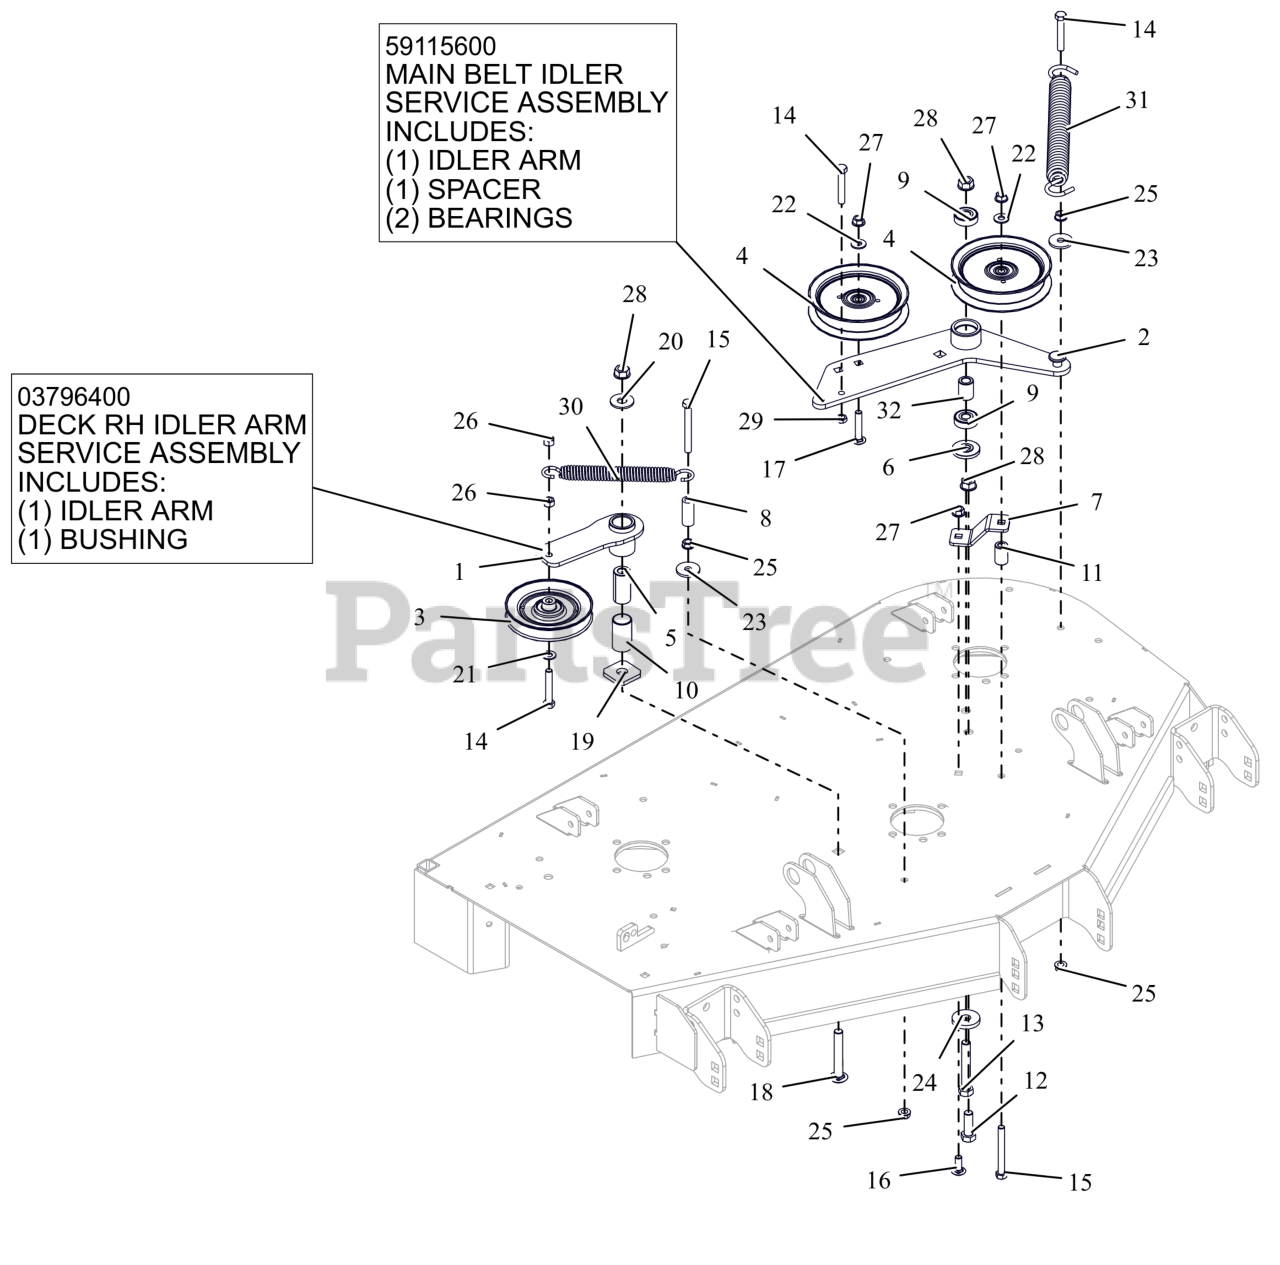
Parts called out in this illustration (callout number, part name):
1	WMT, IDLER ARM - BLACK
1	ASM, IDLER ARM (DECK)
2	WLDMT, DECK PTO IDLR ARM
2	ASSEMBLY, MAIN BELT IDLER
3	IDLER, V-5.00"
4	IDLER, FLAT 5.00"
5	BSHG, SPCR .502X.997X2.03 PM
6	SPACER, IDLER ARM
7	PTO FIXED IDLER MTG BRKT -RED
8	HOSE, .38 X 1.65
9	BRG-BALL .500X1.38X.437
10	BSHG, 1.00X1.125X1.937
11	BUSHING, SLV .380X.750X1.190
12	BLT,HEX .50-13X1.50 G5 ZCC
13	BLT,HEX .50-13X3.25 G5 ZCC
14	BLT,HEX .38-16X2.25 G5 ZCC
15	BLT, HEX .38-16X3.25 G5 ZCC
16	BLT,RHSSN .38-16X1.00 G5 ZCC
17	BLT,RHSSN.375-16X2.00 G5 ZCC
18	BTL,RHSSN .500-13 X 3.25 G5 ZCC
19	WSHR-FLT .640X1.75X.250
20	WSHR,FLT .563X1.375X.109 ZCC
21	WSHR,FLT .406X.812X.065 ZCC
22	WSHR,FLT .375X.875X.083 ZCC
23	WSHR,FLT .406X1.375X.135 ZCC
24	WSHR-FL-STL 0.557X1.625X0.25 ZCC
25	NUT, SPNLK-FLG .38-16 G5 ZCC
26	NUT-LK-CTR .38-16 ZC120
27	NUT-LK-CTR-FLG .375-16 GF ZCC
28	NUT-LK-CTR-FLG .500-13 GG ZCC
29	NUT-JAM .375-16 G2 ZCC
30	SPRING, EXTENSION
31	SPRING, EXTENSION
32	SPACER .510 X .75 X 1.1485
